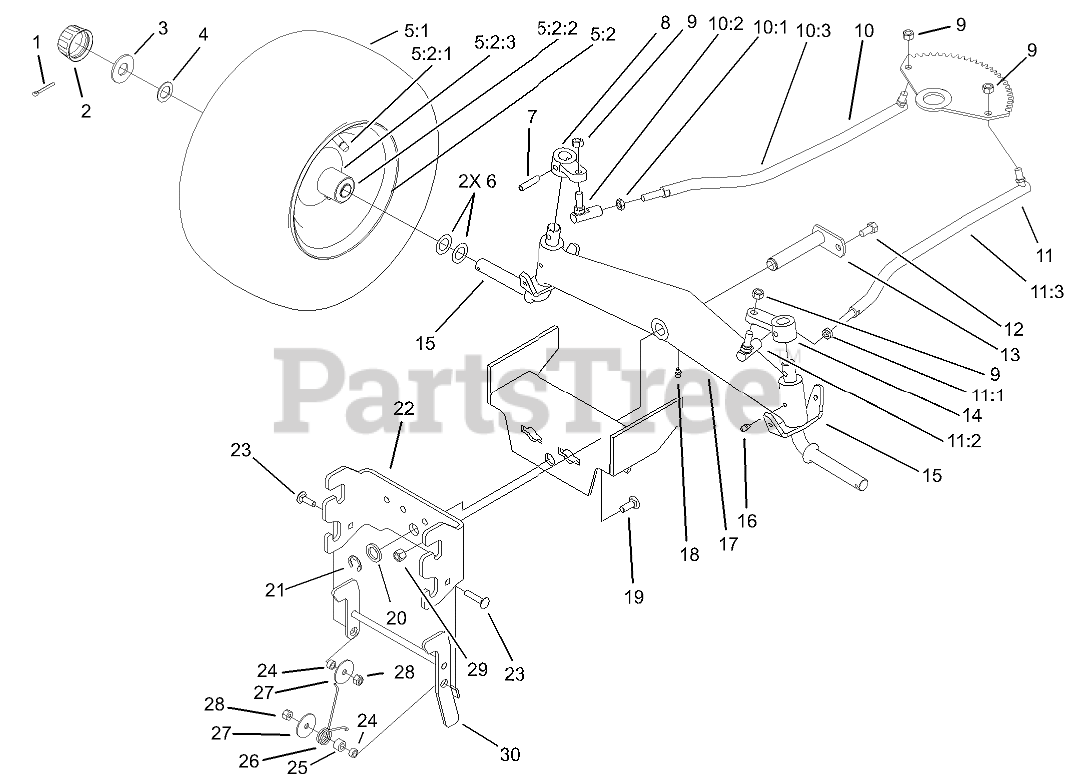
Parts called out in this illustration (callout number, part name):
1	PIN-COTTER
2	CAP-HUB
3	WASHER-PLAIN
4	WASHER
5	FRONT WHEEL & TIRE ASM
5:2	Wheel ASM
5:2:1	VALVE
5:2:2	BEARING-WHEEL
5:2:3	ZERK-GREASE
6	WASHER-SHIM
8	ARM-SPINDLE, LH
10	LINKAGE-STEERING, RH
10:1	NUT-JAM
10:2	BALL-JOINT
10:3	Ball Link ASM
11	LINKAGE-STEERING, LH
11:1	NUT-JAM
11:2	BALL-JOINT
11:3	Ball Link ASM
12	SCREW-HWH, TAPTITE
13	PIN-AXLE
14	ARM-SPINDLE, RH
15	SPINDLE
16	FITTING-GREASE
17	AXLE-FRONT
18	FITTING-LUBE, 45 DEG
19	BOLT-CARR
20	Washer
21	E-RING
22	HITCH-FRONT
23	BOLT-CARR
24	SPACER-YOKE, RIGHT
25	SPACER
26	SPRING-TORSION
27	WASHER-FLAT
28	NUT-LOCK, NI
29	NUT-LOCK, NI
30	LATCH ASM
